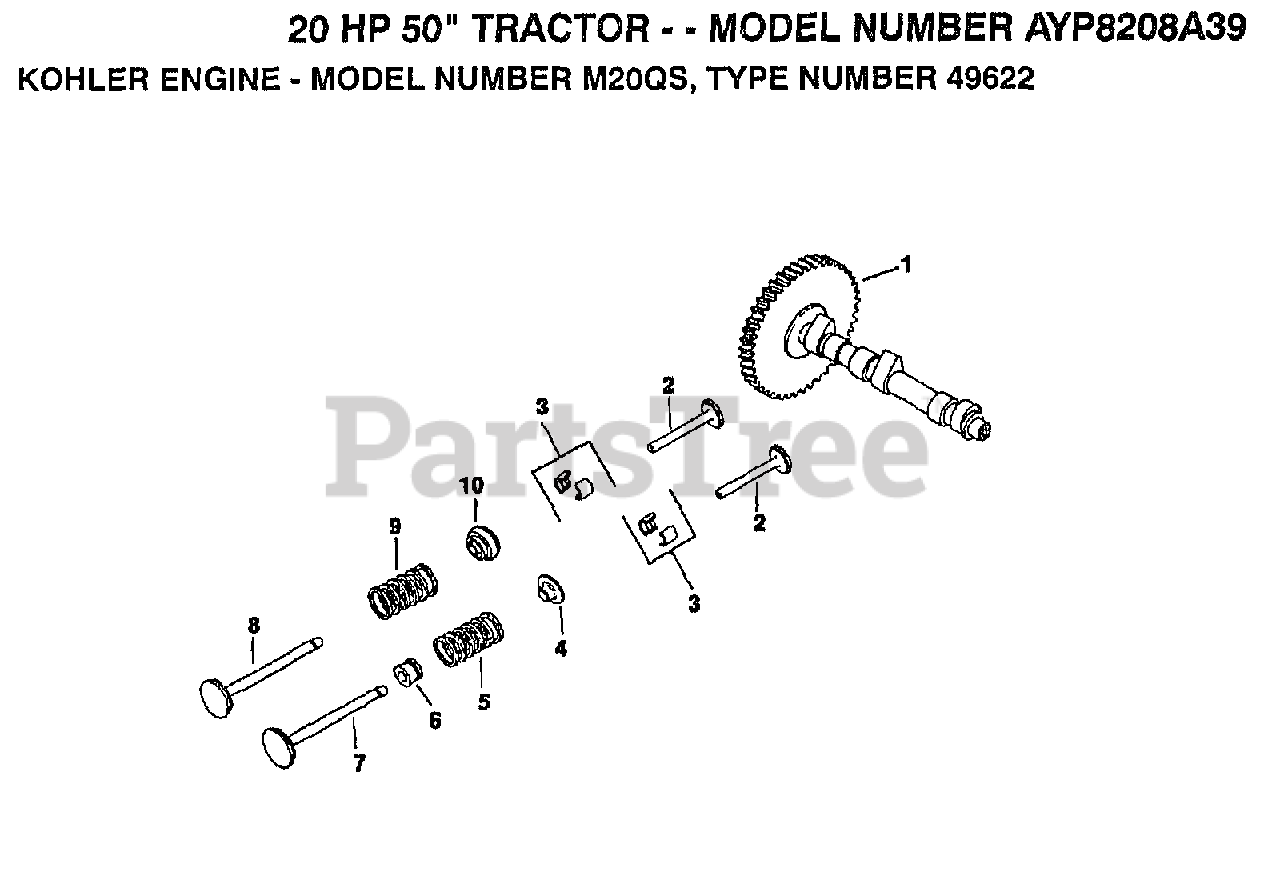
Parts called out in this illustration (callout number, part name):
3	KIT, RETAINER
4	RETAINER, INTAKE VALVE
5	SPRING, EXHAUST VALVE
6	SEAL, INTAKE VALVE STEM
7	VALVE, INTAKE
8	VALVE, EXHAUST
9	SPRING, EXHAUST VALVE
10	ROTATOR, EXHAUST VALVE
